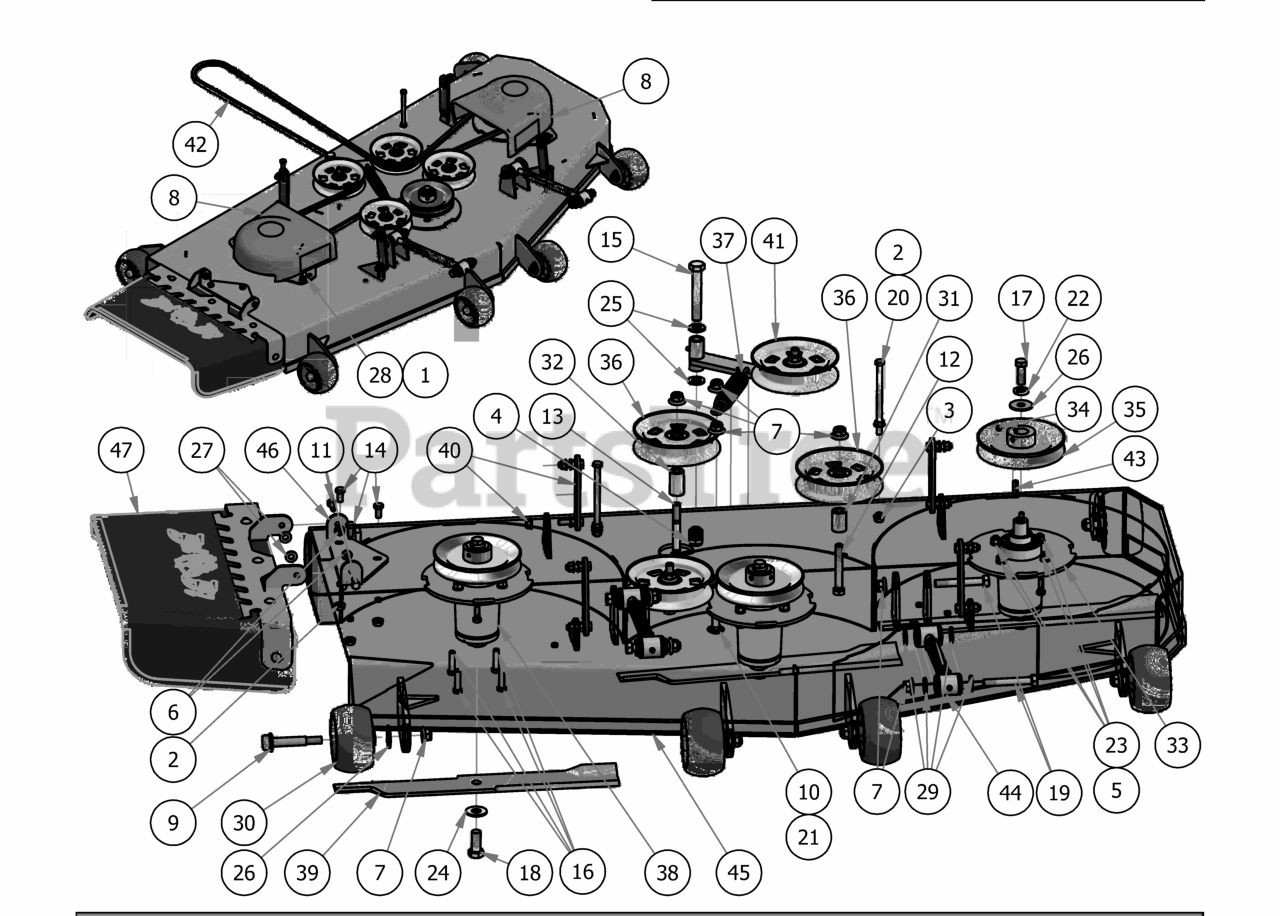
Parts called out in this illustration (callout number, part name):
1	Acorn nut-pulley Cover
2	3/8" Flange Nut
3	3/8" Nylock Flange Nut
4	5/8-11 Nylon Insert Jam Half Nut
5	3/8" Hex Nut
6	5/16" Nylon Flange Nut
7	1/2-13 Nylon Flange Nut
8	Pulley Cover
9	Deck Wheel Bolt
10	1/2 x 2" Carriage Bolt
11	5/16-18 x 1 GR 5 Hex Bolt Zinc
12	1/2 x 3 1/2 Flange Bolt Grade 8
13	1/2" x 4" Bolt (Grade 8)
14	3/8" x 3/4" Hex Bolt
15	5/8" x 4" Hex Bolt
16	3/8 x 1.5" Bolt
17	1/2"-20 x 1 1/2 - Grade 5 Fine Thread Bolt
18	5/8 x 1 1/2 Grade 8 Hex Bolt (Fine)
19	1/2-13 x 3 1/2 GR 5 Hex Bolt
20	3/8-16 x 5 1/2 Hex Bolt
21	.517 Square Hole Round Washer
22	1/2" Lock Washer Zinc
23	3/8" Lock Washer
24	5/8'' Flat Washer
25	.630 ID Plastic Washer
26	1/2" Belleville Washer
27	.360 ID Plastic Washer
28	.360 ID Plastic Washer-Black
29	.505 Nylon Spacer
30	Deck Wheel
31	Idler Pulley Standoff
32	1 3/4" Pulley Spacer
33	Deck Spindle Support Plate
34	5/16 Set Screw
35	6 1/4" Drive Pulley
36	5-3/4 Idler Pulley
37	Deck Idler Spring
38	Spindle Assembly
39	60 Inch Fusion Blade
40	Deck Hanger Assembly
41	2017 MZ/ZT Deck Idler Assembly
43	1/4" x 1" Key
44	2018 Maverick Turnbuckle (Top Link)
45	60 ZT Welded Deck Shell
46	Discharge Chute Hanger (deck mounted)
47	Discharge Chute Assembly
